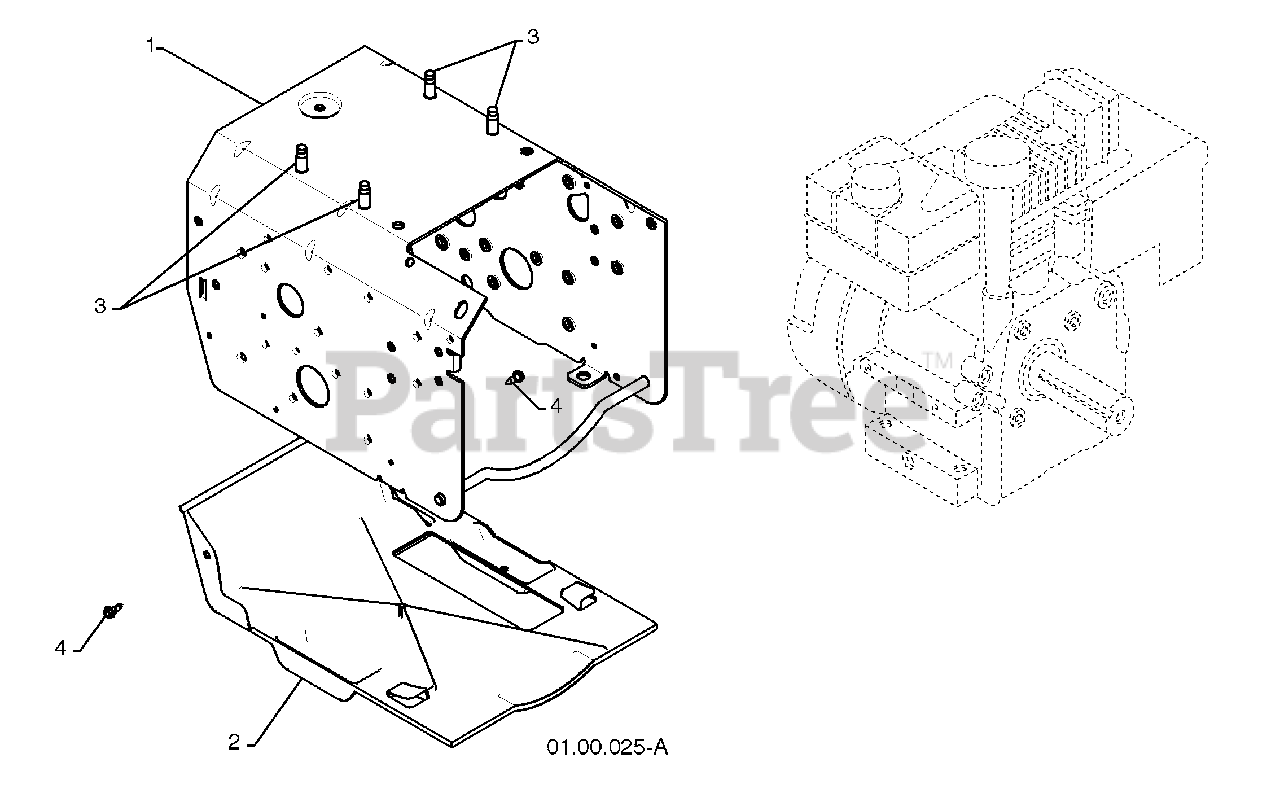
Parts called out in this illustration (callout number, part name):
2	BOTTOM PAN
3	BOLT 3/8-16
4	SCREW 10-24 X .625
